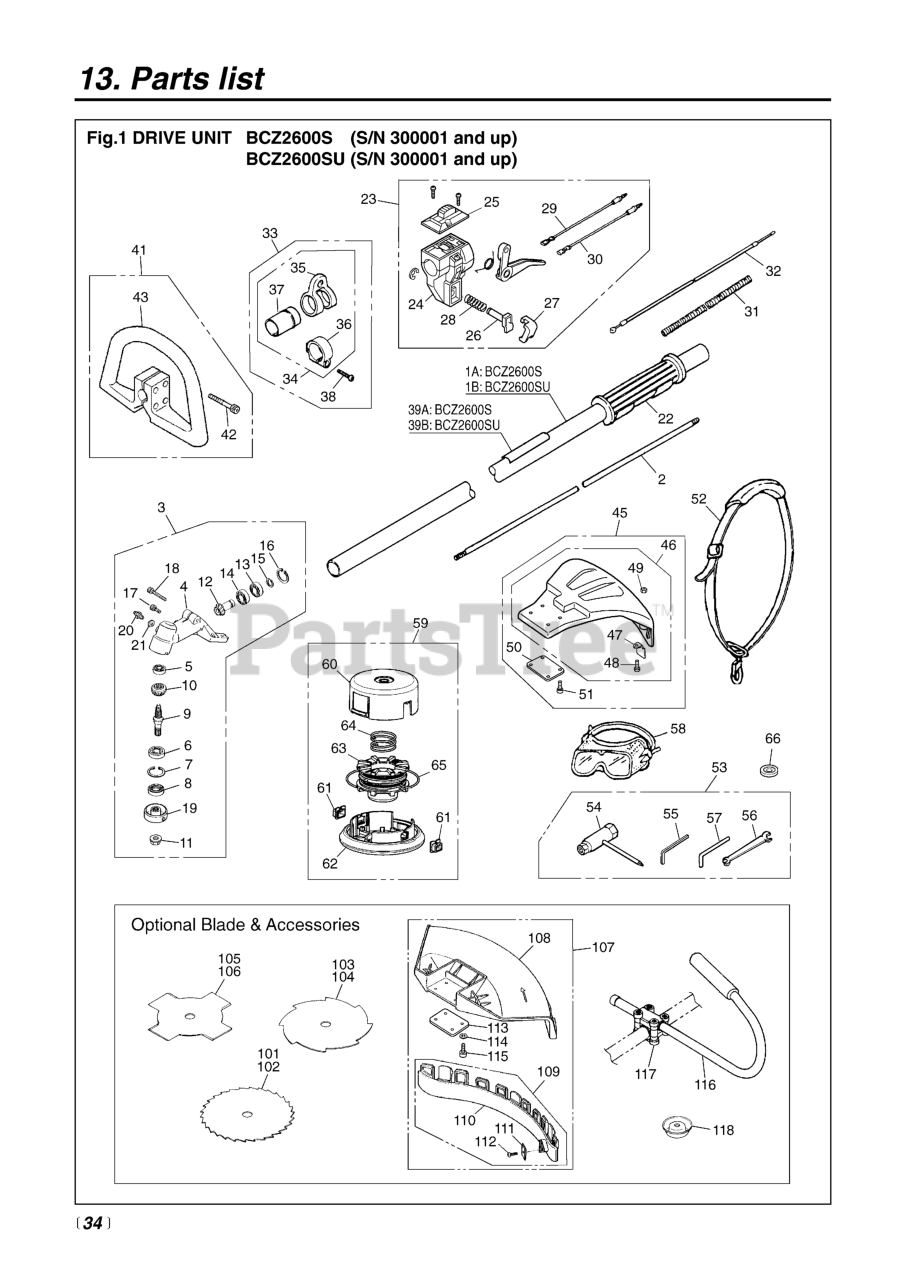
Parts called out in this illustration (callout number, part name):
1A	PIPE COMP (REPLACES -12100)
2	SHAFT (RPLS -12212)
3	GEARCASE ASSY (RPLS -13000)
4	GEARCASE
7	RING, SNAP, M26 X 1.2
8	SEAL, OIL
9	SHAFT
10	GEAR
11	NUT
12	PINION
16	RING, SNAP, M24 x 1.2
17	BOLT, M5 X 10
18	BOLT
19	HOLDER (A)
20	FITTING, GREASE
21	WASHER, M6 X .8
22	GRIP (RPLS 3577-32140 & 3220-
24	LEVER (USE 848-8R2-0313)
25	COVER (USE 848-8RA-0340)
29	CORD (A), BLACK
30	CORD (B), RED
31	TUBE (RPLS 4900-72141)
32	CABLE (RPLS 5580-83100)
33	HANGER ASSEMBLY
34	HANGER COMPLETE
35	HANGER
36	CLAMP
37	SLEEVE
38	SCREW, M5 x 25
39A	LABEL NAME & CAUTION
41	HANDLE ASSY.
42	HANDLE T
43	SCREW, M5 x 30
45	GUARD ASSY (RPLS -24000)
46	GUARD COMP (RPLS. -24100)
47	BLADE (RPLS T3002-24120)
48	SCREW
49	NUT
50	PLATE
51	BOLT (USE 3310-31720)
52	STRAP ASSY. (USE 848-JC0-3610)
54	SOCKET
55	WRENCH (TOOL)
56	SPANNER, 8 X 10 (RPLS 2540- )
57	BAR
58	GOGGLE
59	TAP HEAD COMP.
60	CASE (REPLACES -15111)
61	EYELET
62	COVER (REPLACES -15131)
63	HOLDER, CORD (REPLACES-15141)
64	SPRING
65	CORD
66	HOLDER (B)
101	BLADE, 9
102	BLADE, 9
103	BLADE, 8
104	BLADE, 9
105	BLADE, 8
106	BLADE, 9
107	GUARD ASSEMBLY
108	GUARD
109	PLATE COMPLETE
110	PLATE
111	BLADE
113	PLATE
114	WASHER, SPRING M4 x 1.3
115	BOLT, M5 X 16
116	HANDLE, J
117	BRACKET ASSY (REPLACES -14100)
118	COVER
